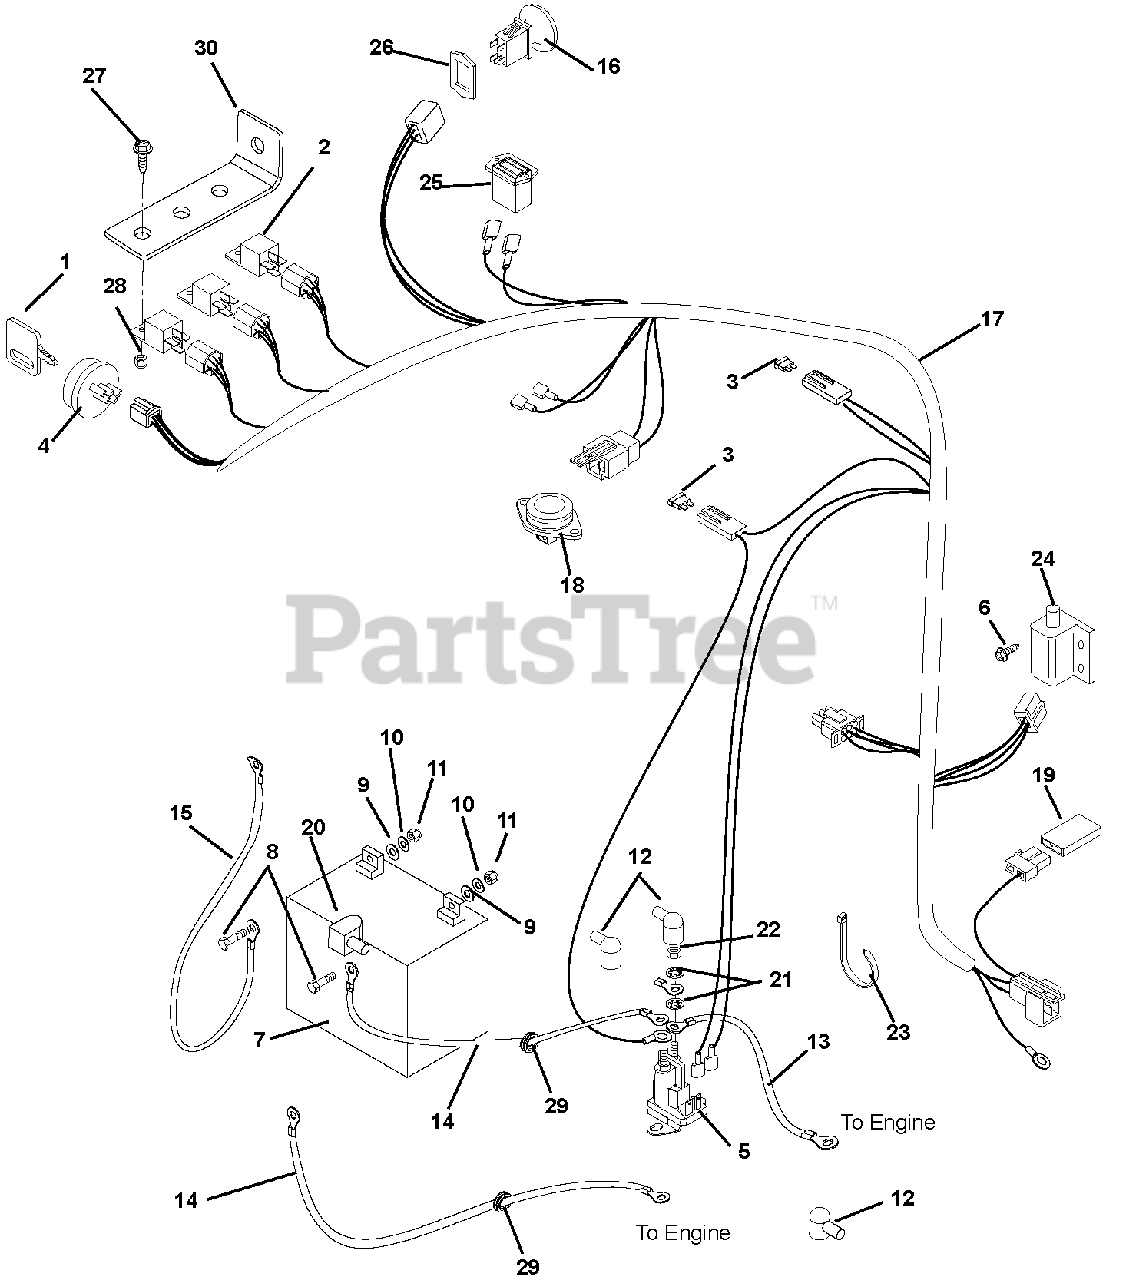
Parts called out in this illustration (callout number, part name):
1	Key with Cap
2	Relay
3	Fuse, 25 AMP
4	Key Switch
5	Solenoid
6	Screw, Tapping 10- 24 x .50 Hex Washer Head
7	Battery, Filled
8	Bolt, Hex .25-20 x .75 Grade 5
9	Washer, Flat Steel .281 x .62 x .065
10	Washer, Locking .25 x .062 Regular
11	Nut, Hex .25-20
12	Boot, Eyelet Terminal
13	Starter Cable 6.75"
14	Starter Cable 16"
15	Ground Cable
16	Switch, Clutch With Retainer
17	Wire Harness, Zoom
18	Switch, Snap Mounting (N.O.)
19	Diode, Connector Shell
20	Insulator
21	Washer, Locking .31
22	Nut, Jam .31-24
23	Cable Tie
24	Switch, Double Pole N.O./N.O.
25	Hour Meter
26	Shim, PTO Switch
27	Screw,Machine 10-24 x .50 Slotted Hex
28	Nut-Locking-Nylon 10-24 with Insert
29	Grommet .125 x 1.000 ID
30	Bracket, Relay
